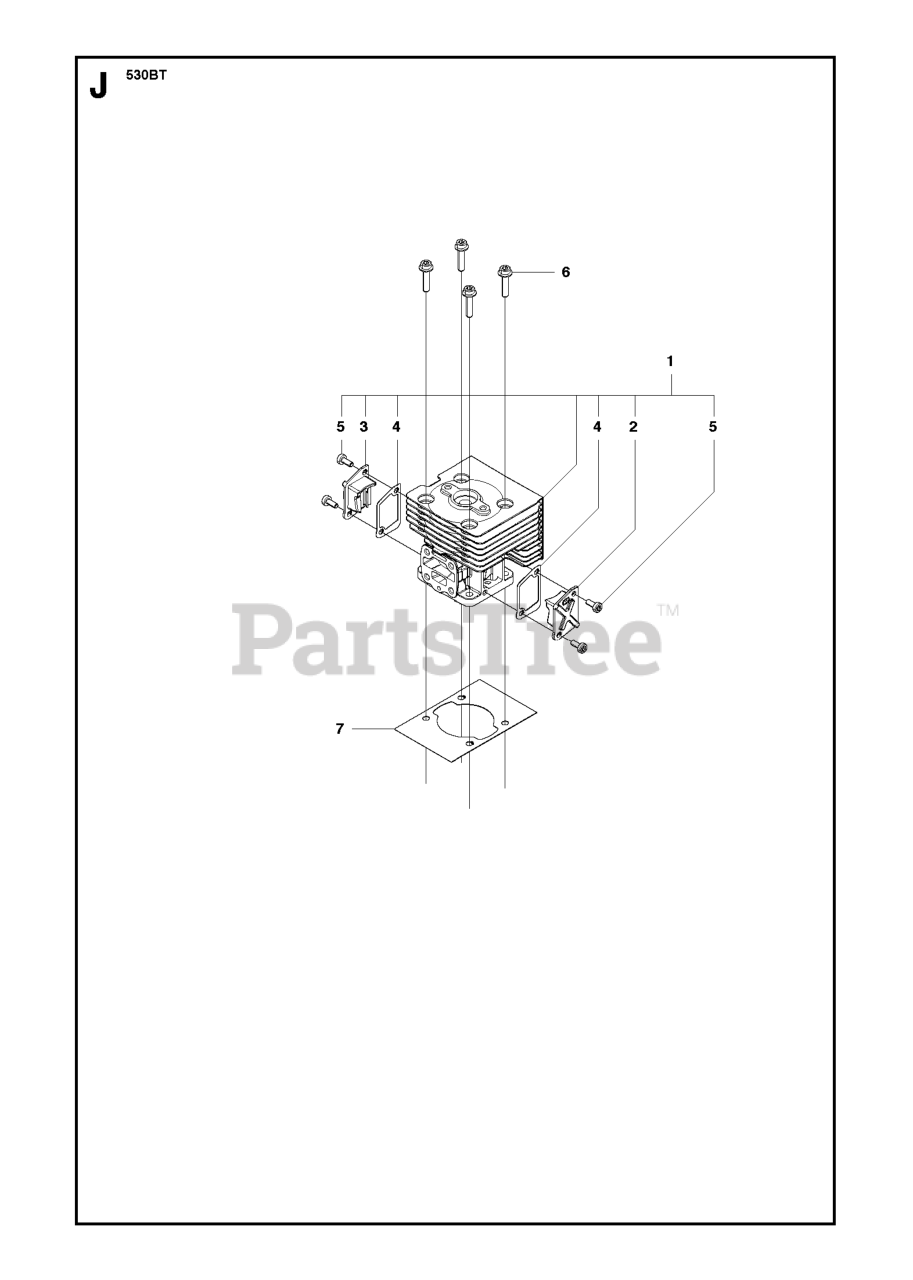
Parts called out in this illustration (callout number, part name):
1	CYLINDER, COMP
2	COVER TR(S)
3	COVER TR (F)
7	GASKET BASE
